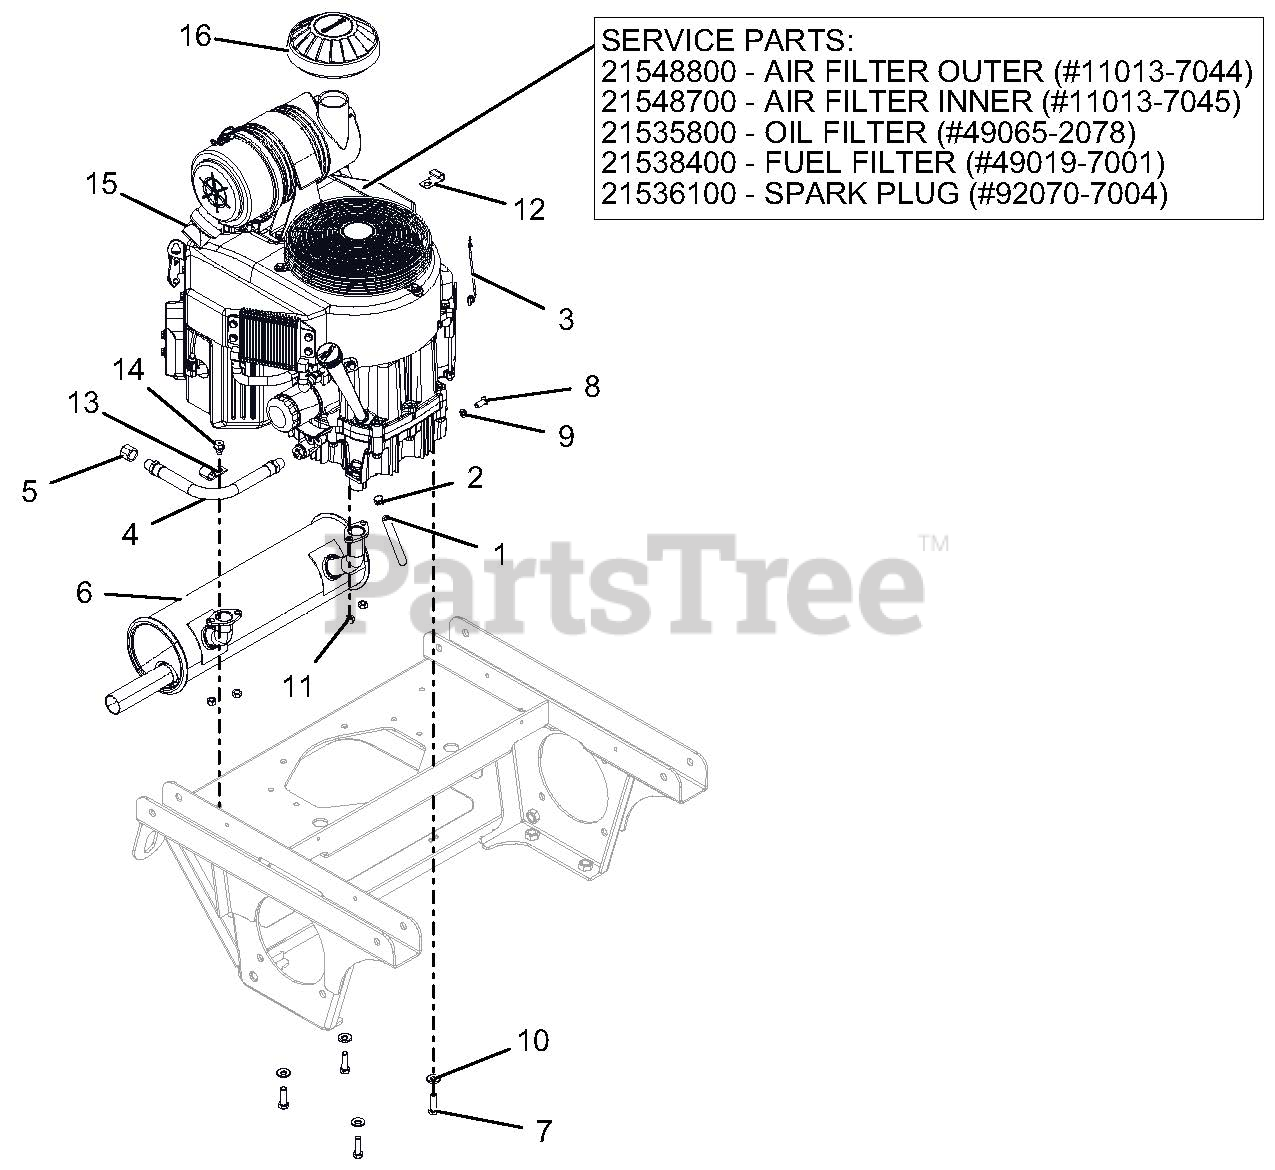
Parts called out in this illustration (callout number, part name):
1	HOSE, .25 LOW-PERM BULK GAS
2	CLAMP, FUEL LINE
3	LEAD - STARTER SOLENOID
4	HOSE,HYD .38-11-0K M6NO-M6N0
5	PIPE CAP 3/8 NPT FEMALE
6	MUFFLER, 27-31 KAW
7	BLT-HEX.38-16X1.25 G5YZ NYTORQ
8	@BLT-HEX M8-1.25X20 YWZC
9	@WSHR-LK .31X.078 REG YWZC
10	WASHER, 3/8" SPRING DISC
11	NUT-LK-TOP M8-1.25 YWZC
14	@SCR-TAP .38-16X.50 HWH TR YWZ
15	ENGINE, KAWASAKI FX850
15	FILTER, OUTER
15	FILTER, INNER - KAW
15	FILTER,OIL - KAW
15	FUEL FILTER - KAWASAKI
15	PLUG, SPARK
16	CAP, AIR CLEANER INTAKE (2")
